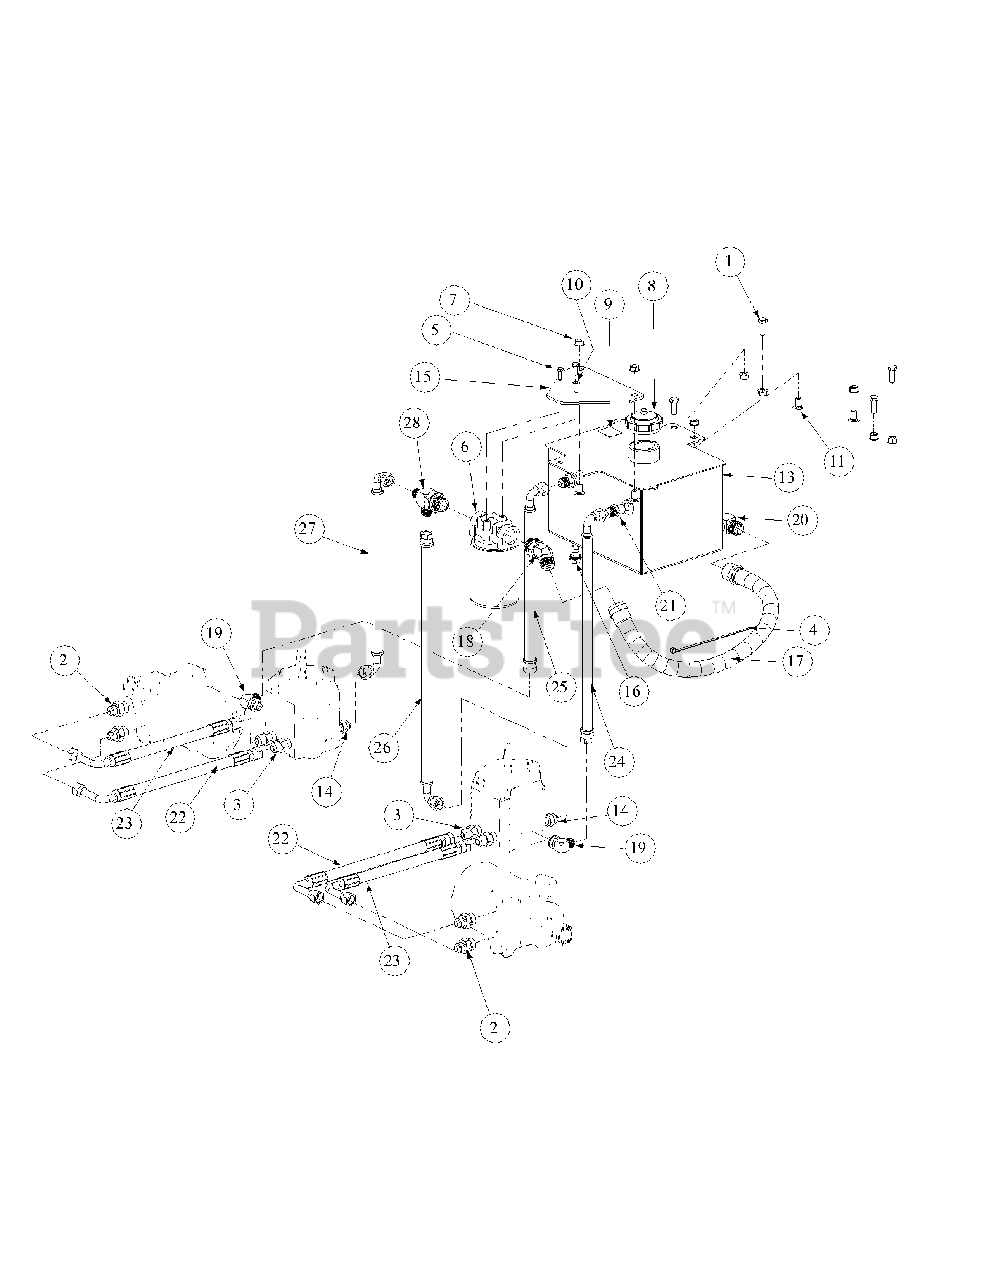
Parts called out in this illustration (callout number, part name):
1	Hex Cap Screw, 3/8-16, 1
2	Fitting 1/2 x 3/4 - O Ring
3	Fitting 1/2 x 1/2 - O Ring to Flare
4	Cable Tie, 3/16 x .05 x 7.4
5	Hex Cap Screw, 1/4-20, .75
6	Filter Head 3/4
7	Hex Nut Flange Lock, 3/8-16
8	Cap, Hydro Oil Tank
9	Decal Oil Only 20W50
10	Lock Washer, 1/4
11	Carriage Bolt, 3/8-16 x .75 LG.
13	Hydraulic Tank Assembly
14	Fitting Connector, 1/2 x 3/8
15	Oil Filter Mounting Plate
16	Oil Pan Drain Plug w/ Seal
17	Tank to Filter Hose Assembly
18	Fitting, 3/4 x3/4 x 45 degree
19	Elbow Fitting, 3/8 O-ring, 1/2 Flare
20	Fitting Elbow, 1/2 x 1/2
21	Fitting, 3/8 NPT, 1/2 Flare
22	Long Pressure Hose Assembly
23	Short Pressure Hose Assembly
24	17.75" Return Hose Assembly, RH
25	14.25" Return Hose Assembly, LH
26	21.25" Supply Hose Assembly, RH
27	15.50" Supply Hose Assembly, LH
28	Tee Fitting, 3/4 x 1/2 x 1/2
